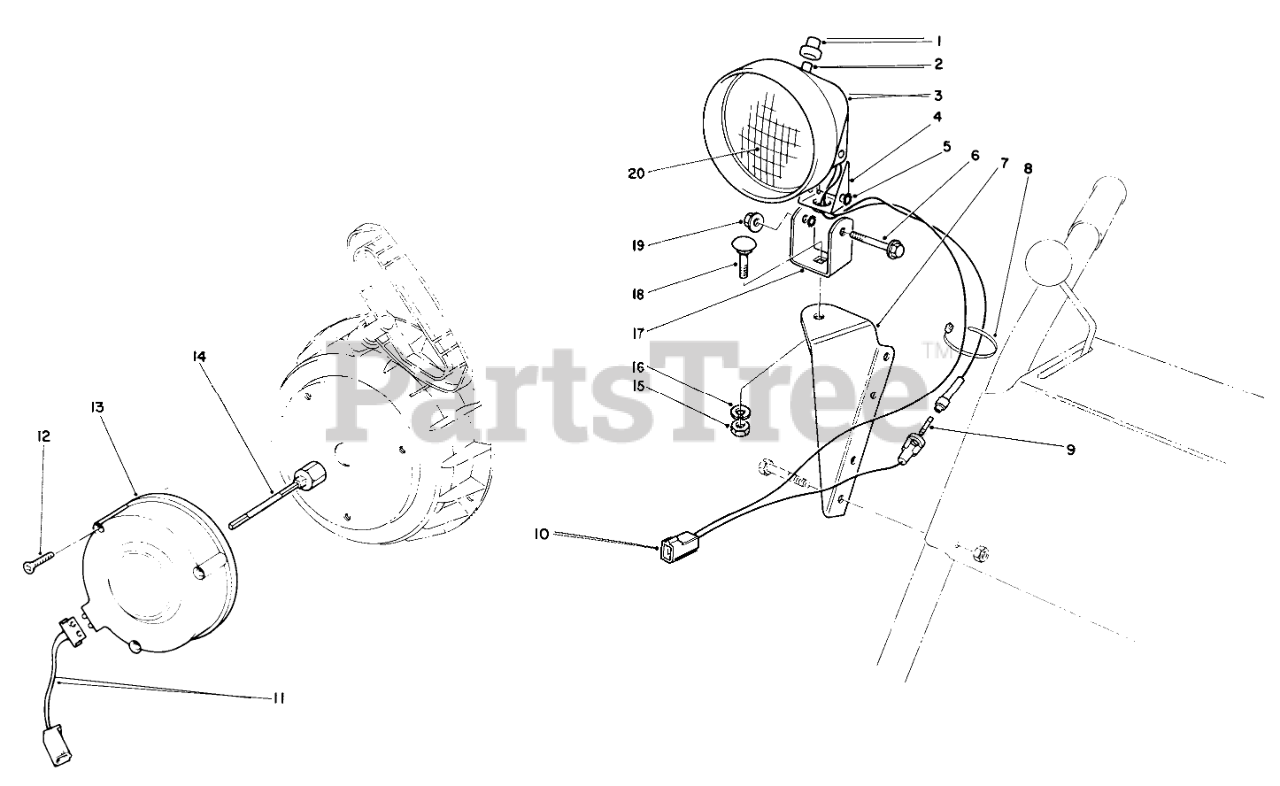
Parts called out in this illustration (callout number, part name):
1	BOOT-SWITCH
2	SWITCH ASM
3	Bucket-Headlamp
4	TO BE DISCONTINED-NOT NEEDED ON PRODUCT
5	WASHER-LOCK
6	SCREW-HH
7	LAMP MOUNT B
8	TIE-CABLE
9	Fuse-7 1/2 Amp.
10	WIRE ASM
11	Connector-Wire
12	SELF TAP SCREW
13	Alternator
14	Shaft-Alternator, 4 Inch
15	NUT-HEX
16	WASHER-LOCK
17	BRACKET
18	BOLT-CARR
19	NUT-HF
20	BEAM-SEALED
